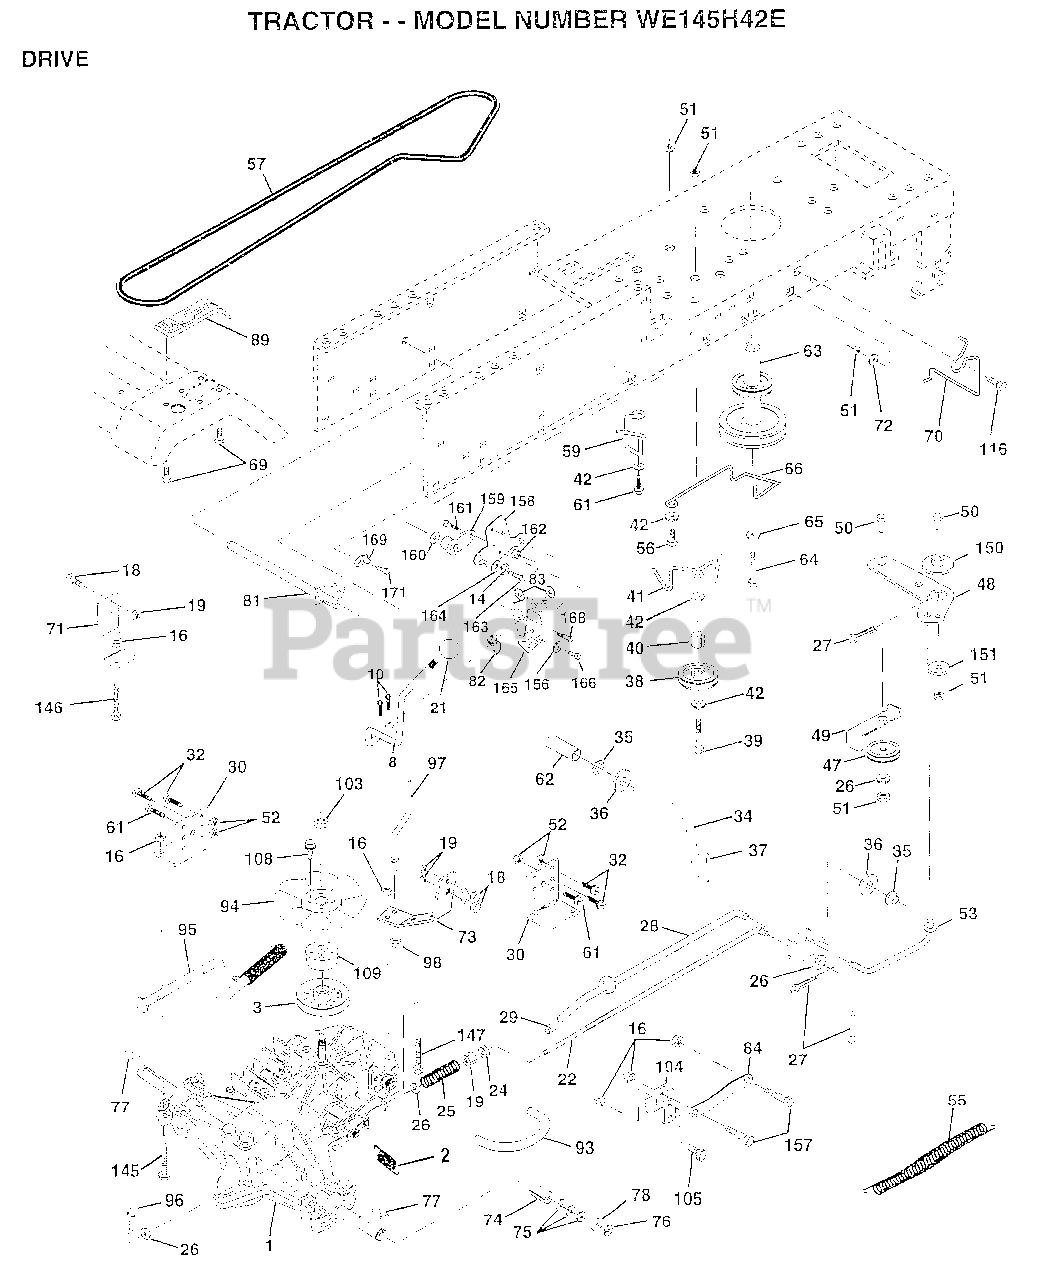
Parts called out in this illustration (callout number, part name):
2	SPRING RET BRAKE
3	PULLEY.4.20.HYDRO
8	ROD.SHIFT.FENDER.ADJ.LT.CRD
10	PIN COTTER 1/8
14	LOCKWASHER
16	NUT
18	BOLT
19	NUT
21	KNOB T (1/2-HOLE)
22	ROD.BRAKE.HYDRO.
24	NUT
25	SPRING ROD LT
26	WASHER
27	COTTER PIN
28	ROD.BRAKE.PARK.LT
29	PLUNGER CAP T
30	TRANSAXLE MTG BKT
32	BOLT
34	SHAFT ASM-PEDAL F
35	NYLON BEARING
36	WASHER LT
38	FLAT IDLER PULLEY
39	BOLT
40	SPACER T
41	"KEEPER,BELT.IDLER FLAT"
42	WASHER
48	BELLCRANK.CLUTCH
49	RETAIN BELT
53	"LINK, CLUTCH T"
55	"SPRING, RETURN LT"
57	BELT-V.HYDR.84.61
59	KEEPER BELT CNTSP
61	SCREW
62	PEDAL COVER T
63	PULLEY.ENGINE
64	BOLT
65	LOCKWASHER
66	KEEPER-BELT
69	SCREW HEXWSH H-L
70	KEEPER BELT ENG
71	STRAP.TORQ.LH.HYD
72	WASHER
73	STRAP.TORQ.RH.HYD
74	SPACER SPLIT
75	WASHER
76	E-RING LT
77	SQUARE KEY
78	WASHER
81	SHAFT ASM.CROSS
82	"SPRING,TORSION"
83	WASHER
84	LINK.TRANSAXLE.HYDR
89	CONSOLE.SHIFT.LT
93	"LINE FUEL HYD 4"""
94	"FAN 7"" HYDRO"
95	CONTROL.ASM.BYPASS.HYDRO.99
96	RETAINER M
97	KEEPER.BELT.RH.HY
98	NUT
104	ARM.CONTROL.PUMP
105	SCREW CAP 5/16-18
108	SCREW.HXHD.10-20
109	ADAPTOR.FAN.HYDRO
116	BOLT RDHD 3/8-16
145	BOLT.HEX.FLGHD
146	BOLT.HEX.FLGHD.
147	BOLT.HEX.FLGHD
150	BUSHING.BELLCRANK.GRD.DR
151	WASHER
156	WASHER.SRRTD.5/16
157	"BOLT,SHOULDER"
158	BRKT.SHIFT.MOUNT
159	HUB.SHIFT
160	WASHER
161	BOLT T
164	WASHER.5/8X.281X10GA
165	BRKT.PIVOT.LEVER
166	SCREW.5/16-18X5/8
168	BOLT.SHOULDER.5/16-18X.561
169	PLATE.FASTENING
171	SCREW LT
